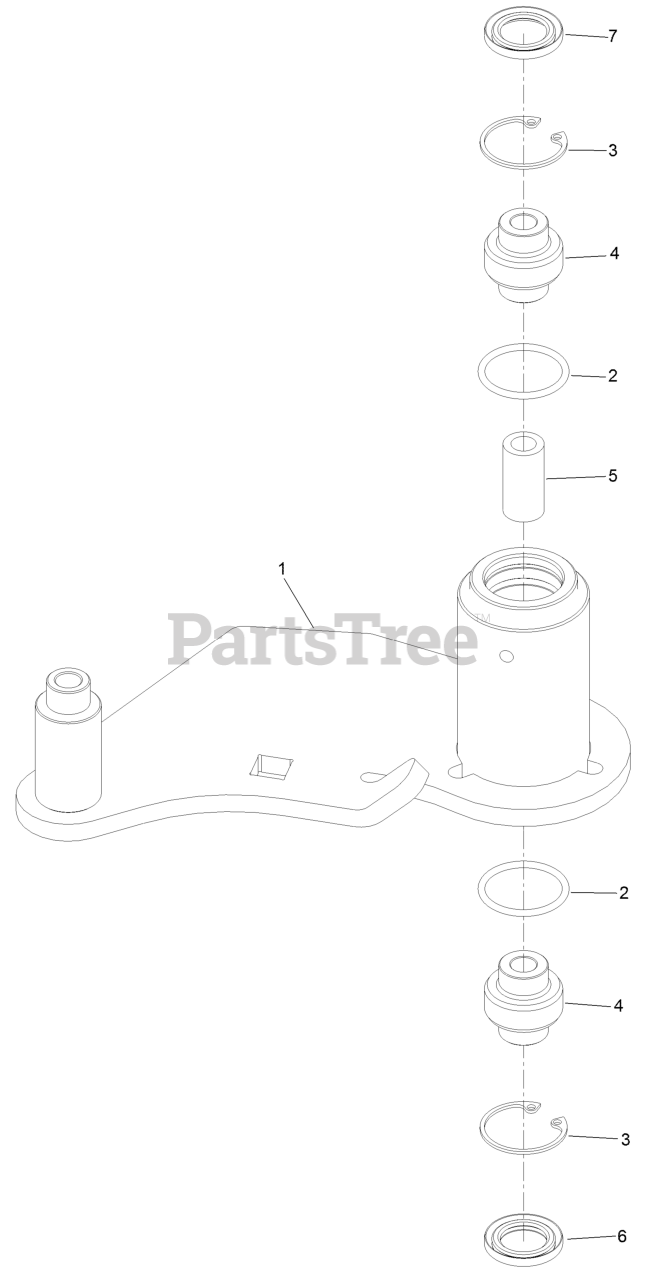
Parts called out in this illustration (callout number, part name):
1	Idler-Deck
3	RING-SNAP
4	BEARING-SPHERICAL
6	SEAL-LIP, DOUBLE
7	SEAL-LIP, SINGLE
